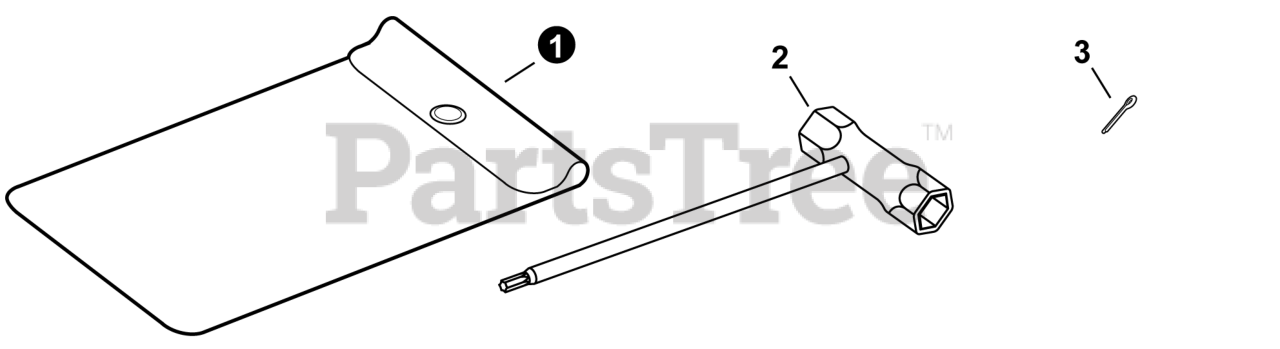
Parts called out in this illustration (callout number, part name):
1	BAG, TOOL
2	T-WRENCH
3	PIN, COTTER 2x22
